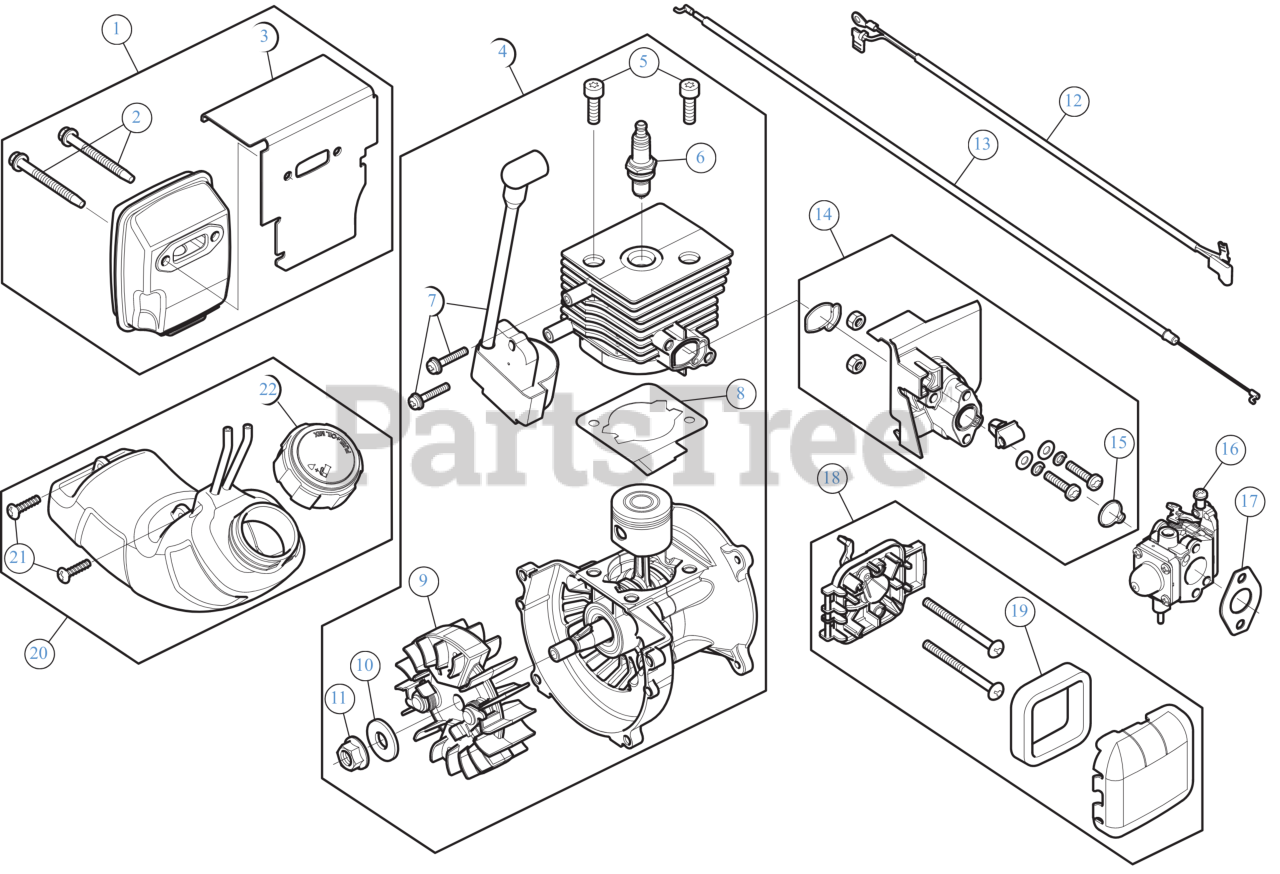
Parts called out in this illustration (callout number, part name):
1	MUFFLER ASSEMBLY 27CC
2	MUFFLER SCREW
3	MUFFLER GASKET
4	SHORT BLOCK
5	SCREW 1/4 x 20 x .8125
6	SPARK PLUG
7	MODULE ASSEMBLY MPP
8	GASKET CYL
9	FLYWHEEL ASSEMBLY
10	WASHER .406X1.0X.095
11	NUT 3/8-24
13	THROTTLE CABLE
14	INTAKE ASSEMBLY
16	CARBURETOR ASSEMBLY
17	GASKET CARB
18	AIR CLEANER ASSEMBLY
20	FUEL TANK ASSEMBLY
21	SCREW 8-16 x 3/4
